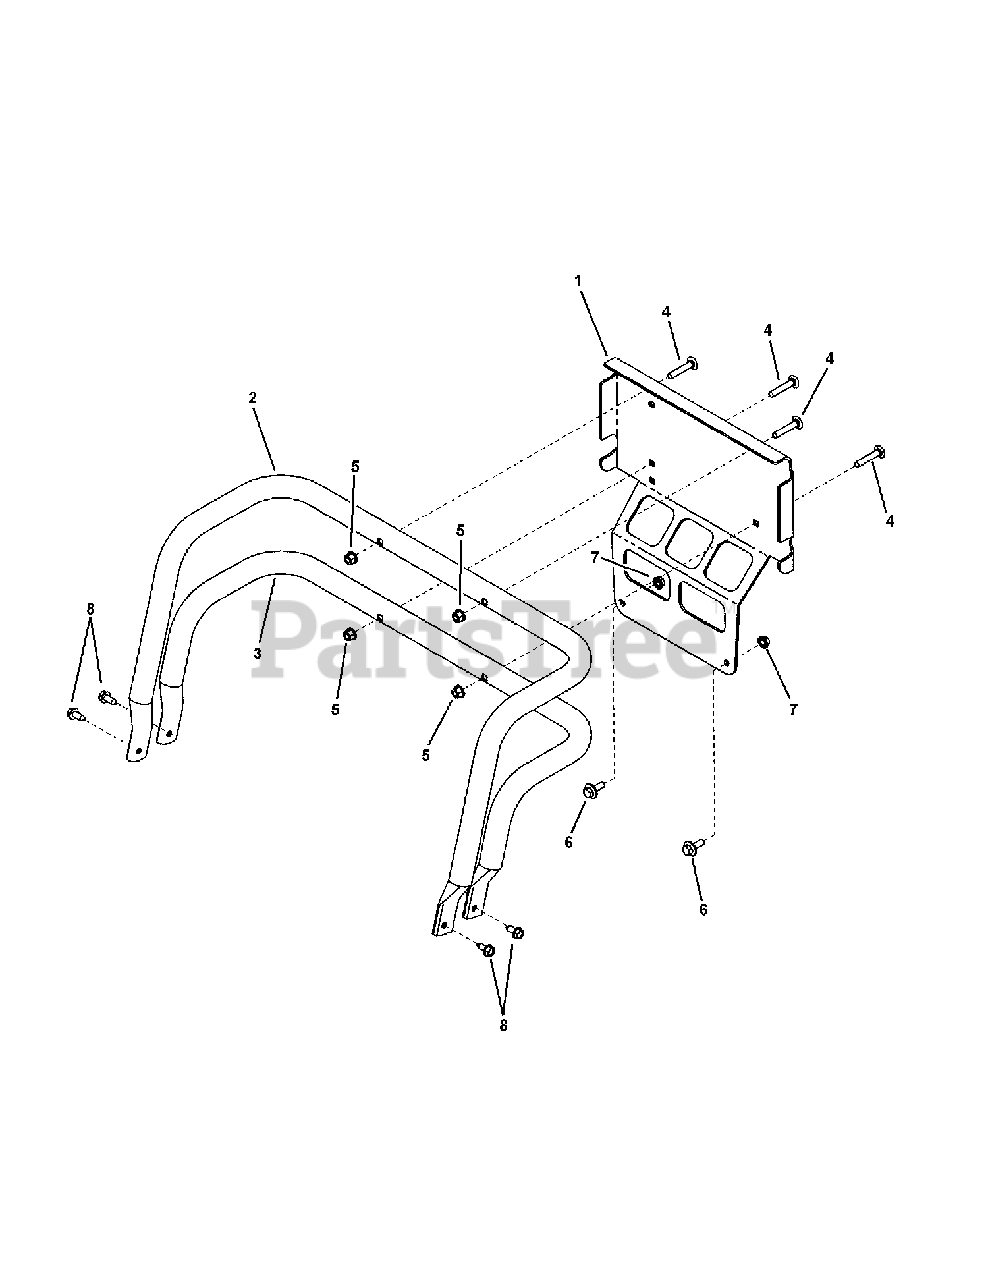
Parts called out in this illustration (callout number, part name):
1	PLATE, Brand, Simplicity
1	PLATE, Brand, Massey
2	TUBE, Bumper, Upper, 285Z
3	TUBE, Bumper, Lower, 285Z
4	BOLT, 5/16-18 x 1-3/4" Round Head Short Square Neck
5	NUT, 5/16-18 Hex Flange Nyloc
6	BOLT, Shoulder
7	NUT, 5/16-18 Hex Flange Lock, Large, Black
8	SCREW, 5/16-18 x 3/4" Hex Washer Head Self-Tap, Black
